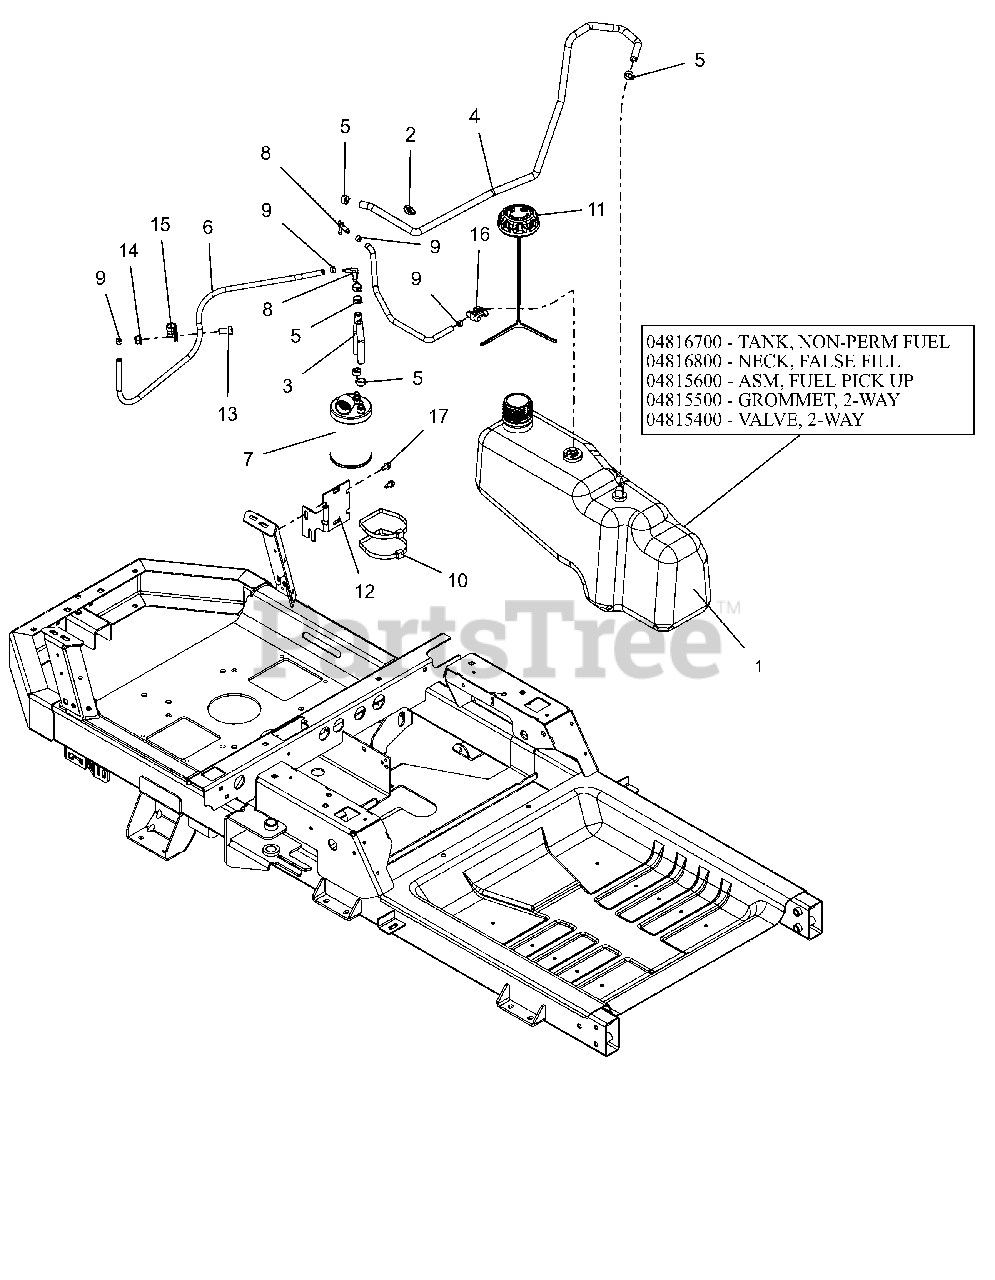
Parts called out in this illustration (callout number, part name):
1	ASM,TANK NON-PERM FUEL
1	TANK, ZOOM/ZT NON-PERM, FUEL
1	NECK, FALSE FILL ZOOM/ZT
1	ASM, FUEL PICK-UP ZOOM/ZT 2015
1	GROMMET, 2-WAY
1	VALVE, 2-WAY
2	ROUTING CLIP (1/2" ID)
3	HOSE, .25 LOW-PERM BULK GAS
4	HOSE, .25 LOW-PERM BULK GAS
5	CLAMP, FUEL LINE
6	HOSE, .188 LOW-PERM BULK GAS
7	CARBON CANISTER, 300CC
8	FITTING-3/16X1/4 90DEGREE VAC
9	CLAMP-HOSE, SPRING .188
10	P-PLASTIC TIE STRAP LARGE
11	CAP, FUEL VENT-IN 2.25" RATCH.
12	BRKT, CARB CANISTER MOUNT
13	@BLT-HEX .38-16X.75 GR5 YWZC
14	@NUT-LK-NYL-FLG .38-16 YWZC
15	CLAMP, CUSHIONED STEEL
16	CLIP, T, .38-.50
17	SCR-TAP .25-20X.50 HWH TR YWZ
